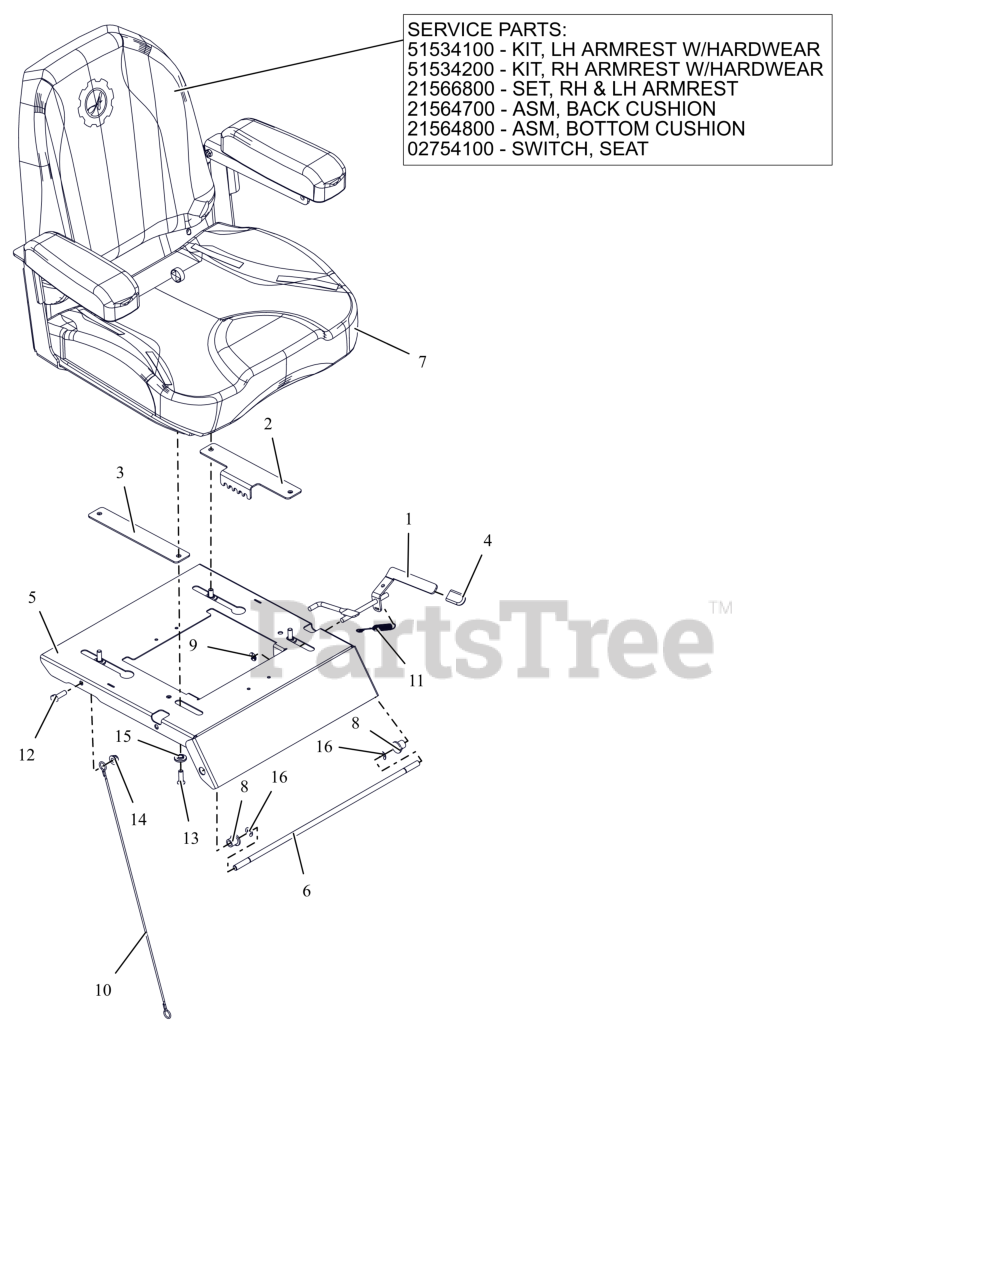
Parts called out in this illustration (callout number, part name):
1	WLDMT, ADJUSTABLE SEAT LATCH
2	PLATE, ADJUSTABLE SEAT TRACK
3	PLATE, ADJUSTABLE SEAT SLIDE
4	GRIP, SEAT LEVER, GREY
5	PLATE, SEAT
6	ROD, SEAT PIVOT
7	SEAT, IKON XL
7	KIT, ARMREST LH W/HDWR
7	KIT, ARMREST RH W/HDWR
7	SET, LH & RH ARMREST
7	ASM, BACK CUSHION-ARIENS X
7	ASM, BOTTOM CUSHION-ARIENS X
7	SWITCH- SNAP MTG N.O.
8	BSHG-FLG .38X.580X.667X.750
9	NUT-PUSH .312
10	LANYARD, SEAT CABLE .093X19.5
11	SG-TENS .043X.44X3.31 WLD 5.8
12	BLT,HEX .31-18X1.00 G5 ZCC
13	BLT,SHCS-BTN .31-18X1.00 ZCC
14	NUT,LK-NYL-FLG .31-18 G5ZC120
15	BSHG, FLG .312X.499X.23X.88
16	RG-RTNG-EXT .375X.035 TYP E
